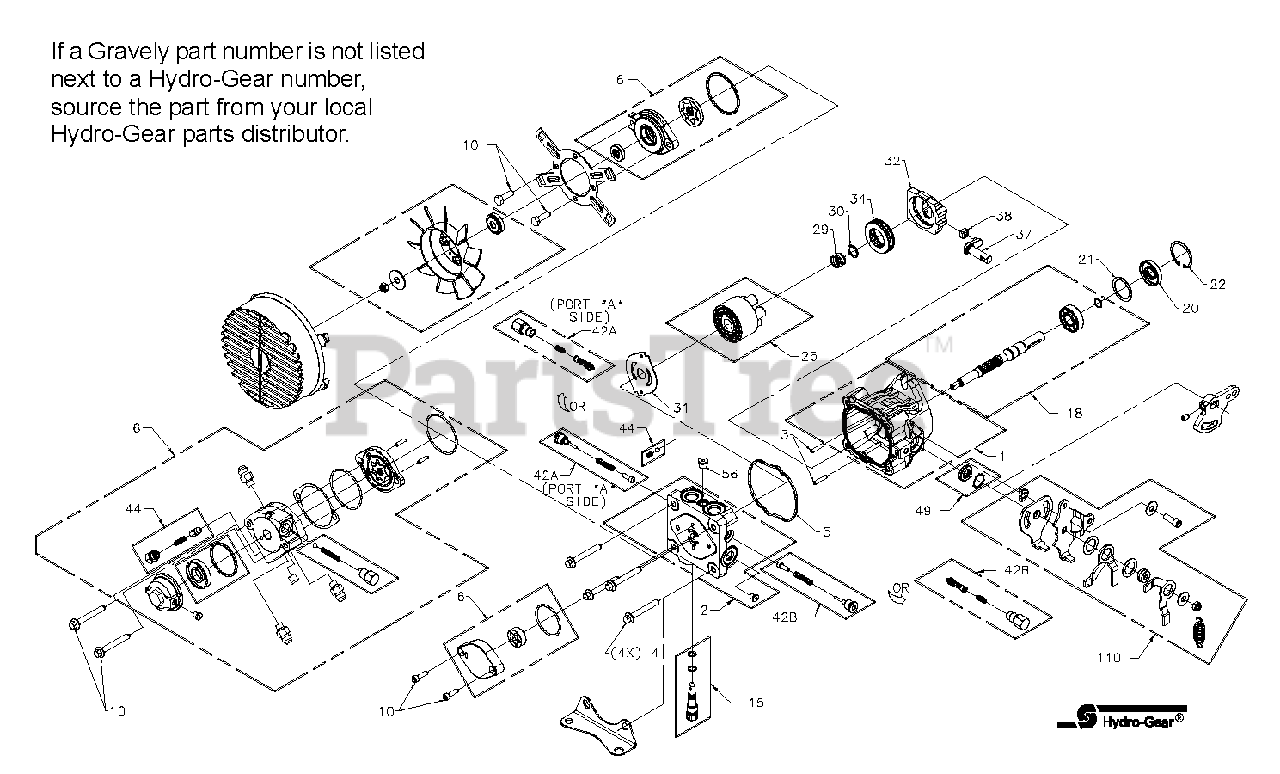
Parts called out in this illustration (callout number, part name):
1	Kit, Housing
2	Kit, End Cap w/Poppets
3	Straight Headless Pin
4	Hex, Flange Bolt M8-1.25 x 60mm
6	Kit, Chg Pump
10	Cap Screw 5/16-18
15	Kit, Bypass
18	Kit, Pump Shaft (15mm Straight Keyed, Thru)
20	Lip Seal 17 x 40 x 7 PTC
22	Retaining Ring
25	Cylinder Block Kit
29	Block Spring
30	Block Thrust Washer
31	Valve Plate
32	Swashplate
34	Ball Thrust Bearing
37	Arm, Trunnion, Tapered Square
38	Slot Guide
42	Kit, Shock Valve (200 Bar .031 Orifice)
44	Kit, Charge Relief Valve
49	Trunnion Seal - Retainer Kit
56	Plug, Straight Thread
110	Kit, Return
NS	Overhaul Seal Kit
